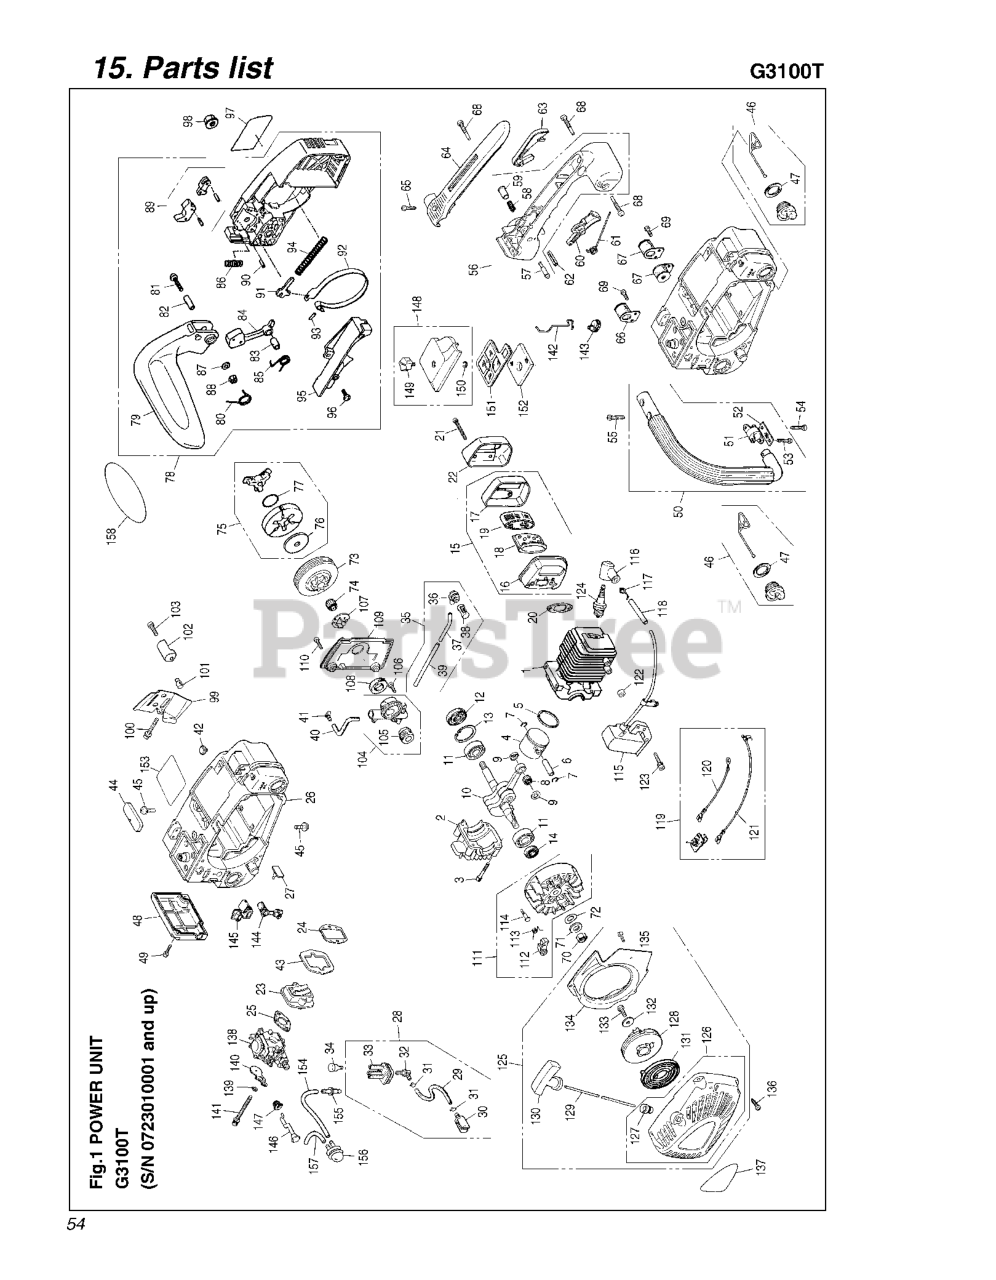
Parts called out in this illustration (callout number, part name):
1	CYLINDER
2	CRANKCASE
5	RING.PISTON
10	CRANKSHAFT
19	ARRESTER
24	GASKET-REED
28	FUEL PIPE ASSY
31	CLIP
32	ELBOW
33	GROMMET (RPL 50030318)
34	BREATHER
46	CAP ASSY
62	SPRING PIN
63	ARM (RPLS 335633350-335633352)
69	SCREW
73	DRUM.3/8-6
75	CLUTCH ASSY
83	SPACER
85	SPRING
86	SPRING (RPLS 285154270)
89	BRAKE LEVER
90	ROLLER
91	ARM
93	ROLLER
94	SPRING
96	SCREW
98	NUT FLANGE
118	TUBE (RPLS 263072210)
119	SWITCH
135	SCREW
138	CARBURETOR ASSY
142	ROD.THROTTLE
146	ROD.CHOKE
148	COVER
156	PRIMARY BTN
